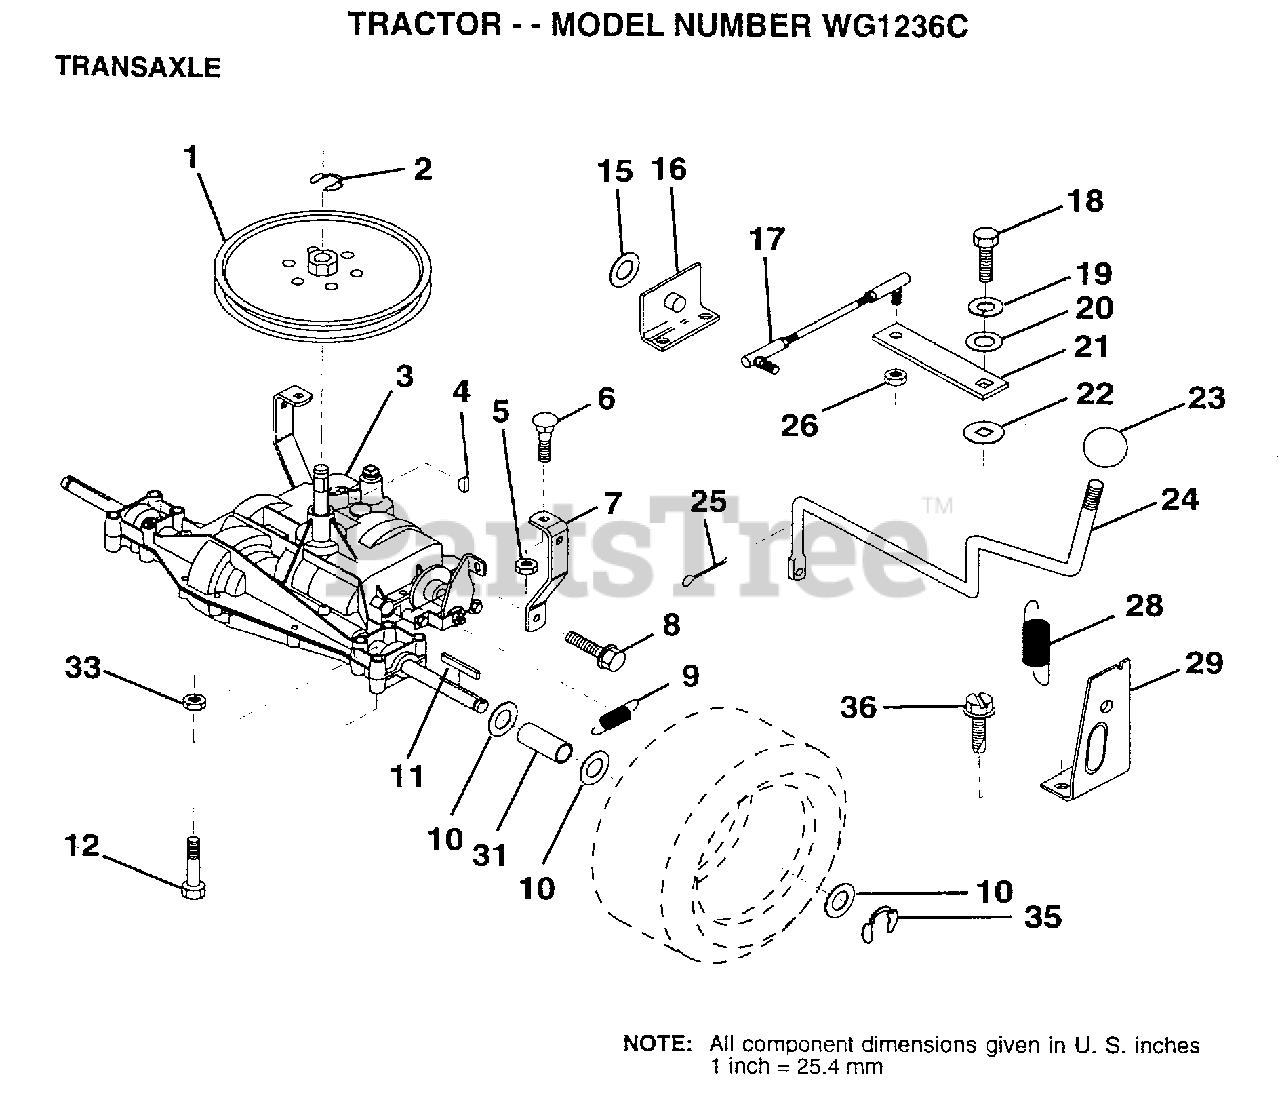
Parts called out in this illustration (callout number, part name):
1	PULLEY
6	BOLT
7	"STRAP,TORQUE"
8	SCREW
9	SPRING.BRAKE.RETU
10	WASHER
11	SQUARE KEY
12	BOLT
16	"SUPT,HDLE SHT LH"
17	"LINK,SHIFT"
18	BOLT.1/4-28.W/PAT
19	LOCKWASHER
20	WASHER LT
21	"ARM,SHIFT"
22	WASH-SHFT PLT LT
23	KNOB T (1/2-HOLE)
24	"ROD,SHIFT"
25	PIN COTTER 1/8
26	NUT.LOCK.5/16-24
28	"SPRING,EXT"
29	"SUPT,HDLE RH"
31	SPACER LT
35	E-RING LT
36	SCREW
